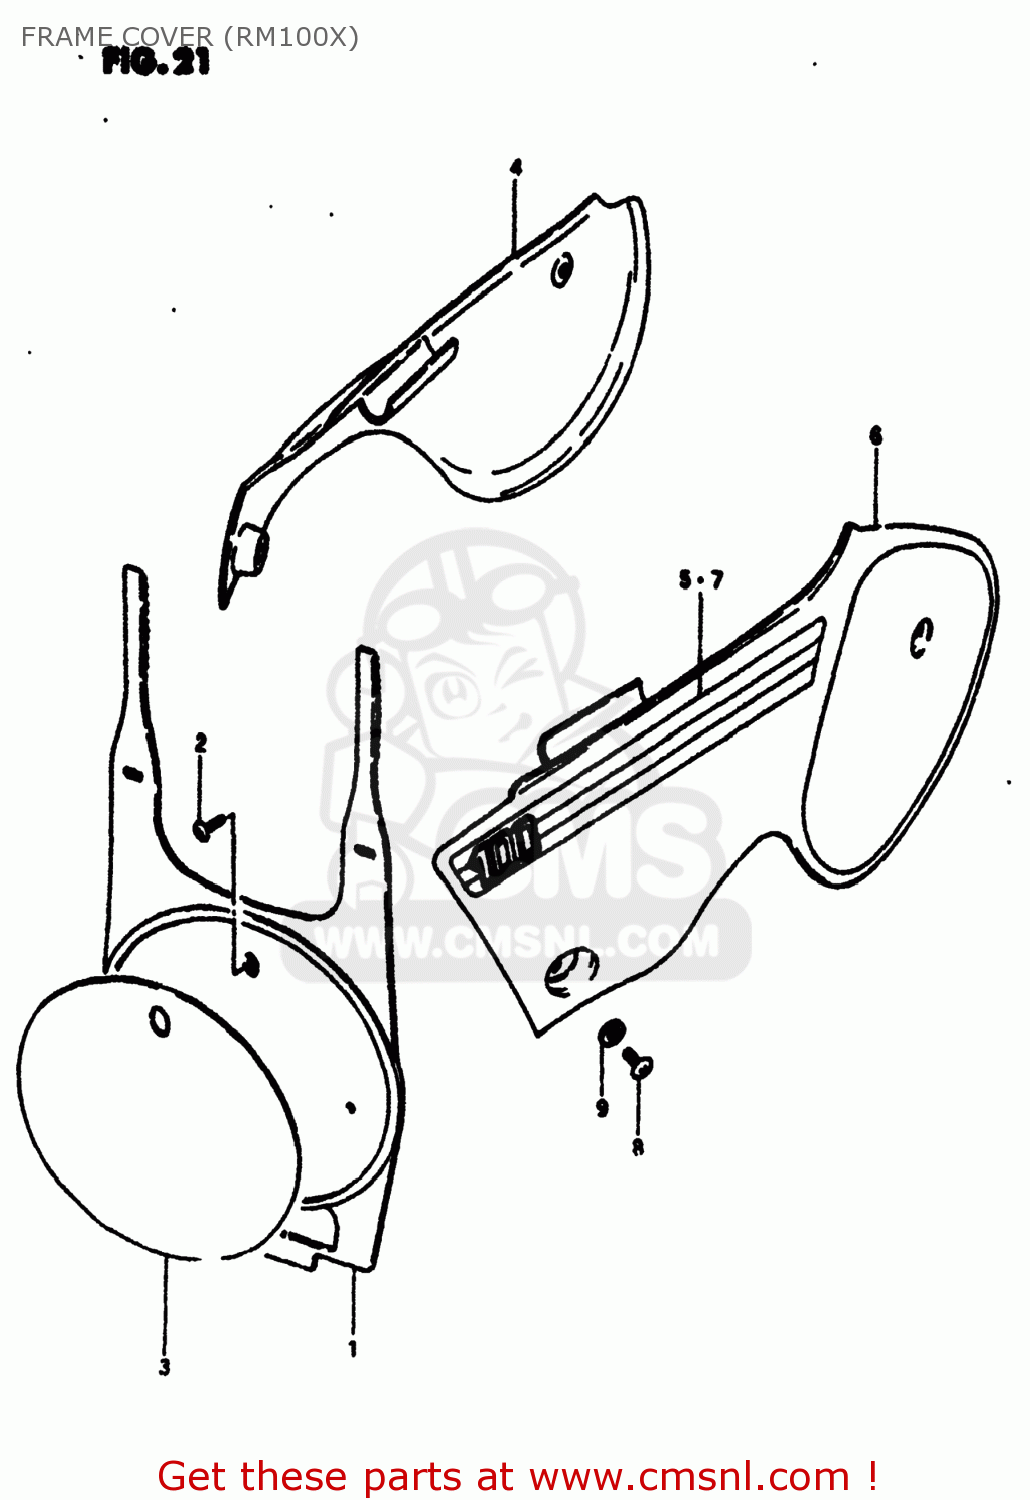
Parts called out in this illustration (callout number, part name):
1	PLATE,NUMBER,FRONT
2	(5X20) CROSS SCREW
3	EMBLEM,FRONT NUMBER PLATE
4	COVER,FRAME,RIGHT
5	TAPE,FRAME COVER
6	COVER,FRAME,L(YELLOW)
7	TAPE,FRAME COVER
8	SCREW
9	WASHER
